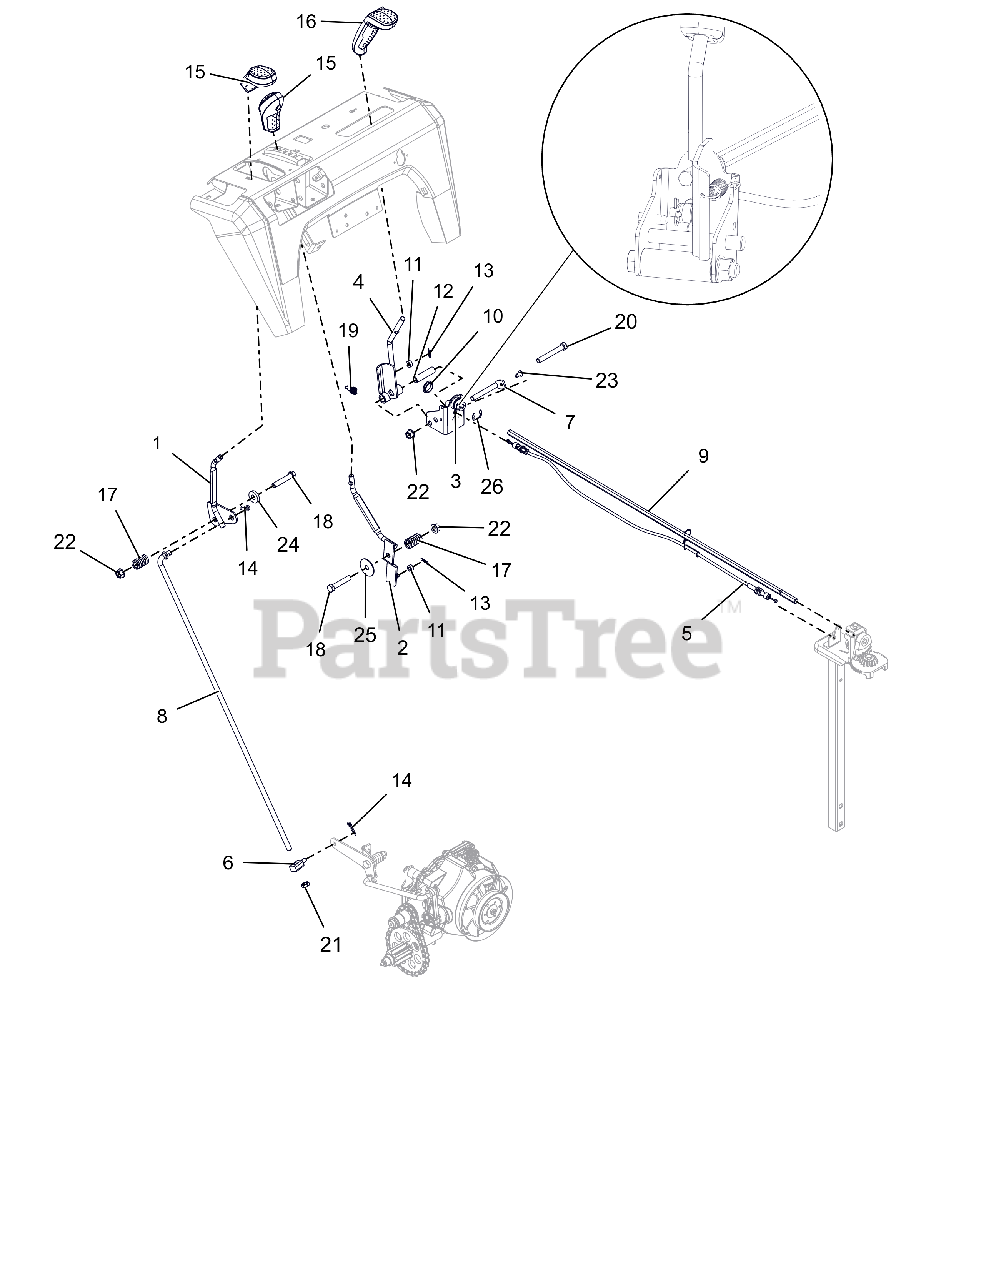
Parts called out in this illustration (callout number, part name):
1	WELDMENT,LG DASH SPEED CONTROL
2	WELDMENT,LG DASH DEFL CONTROL
3	WELDMENT-CONTROL BRACKET-CHUTE
4	WELDMENT, CONTROL LEVER
5	CABLE, CHUTE LOCK, PRO
6	PIVOT,SHIFT ROD .375-16(TRUNN)
7	ROD, PIVOT - INTERLOCK
8	ROD, SHIFT-PRO
9	ROD, HEX - CHUTE ROTATION
10	BUSHING, POLYLINER-.75 SNAPIN
11	BSHG-SLV .265X.500X.219
12	SPCR, WHEEL .385X.500X2.00
13	PIN-HAIR INT .06X.18X.77
14	PIN-HAIR INT .08X.18X1.18 YWZC
15	KNOB, CONTROL, DASH
16	HANDLE, QUICK TURN, ASM
17	SG-COMP .125X.781X1.250
18	@BLT-HEX .38-16X2.00 GR5 YWZC
19	SPRING-EXT .047X.438X1.45
20	@BLT-HEX .38-16X2.75 GR5 YWZC
21	NUT-HEX-JAM .375-16 YWZC
22	@NUT-LK-TOP-FLG .38-16 YWZC
23	SCR-TAP .25-20X.50 HWH TR YWZ
24	WSHR-FL-STL .406X1.00X.188 YWZ
25	WSHR-FL-STL .380X1.50X.062 YWZ
26	E-RING .750X.050
